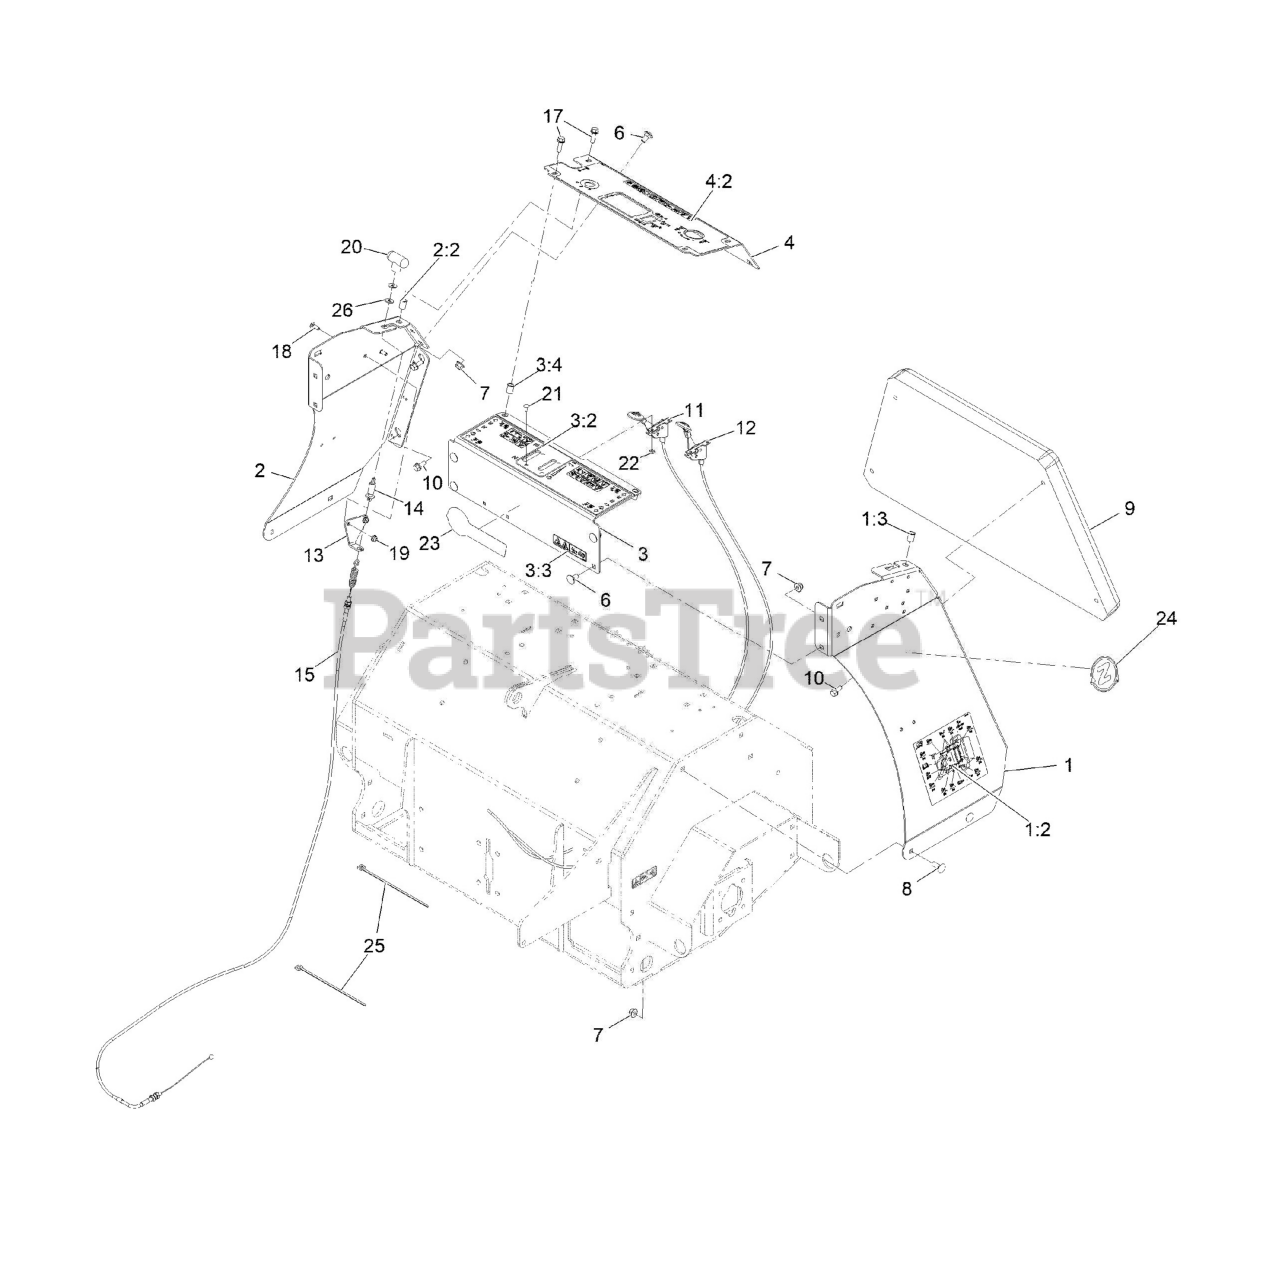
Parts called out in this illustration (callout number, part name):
1	Panel-Side, LH
1:2	DECAL-SERVICE AID CE
1:3	NUT-CLINCH
2	ASM-PANEL,SIDE RH (BLACK)
2:2	NUT-CLINCH
3	ASM-Plate W/Decal
3:2	DECAL-WARNING, CONTROL PA
3:3	DECAL-WARNING, TINES
3:4	NUT-CLINCH
4	ASM-Panel W/Decals
4:2	Decal-Panel, Control
6	SCREW-CARR
7	NUT-HF, NI
8	BOLT-CARR
9	CUSHION, GREY
10	SCREW-HHF
11	CONTROL-CHOKE
12	CONTROL-THROTTLE
13	BRACKET-CABLE, BRAKE
14	LINK-CABLE, BRAKE
15	CABLE-BRAKE
17	SCREW-HHF
18	BOLT-CARR
20	KNOB-TEE
21	BOLT-CARR
22	NUT-LOCK, NI
23	DECAL-Z-AERATE 30 LOGO
24	Decal-Z-Logo
25	TIE-CABLE
26	WASHER-FLAT
